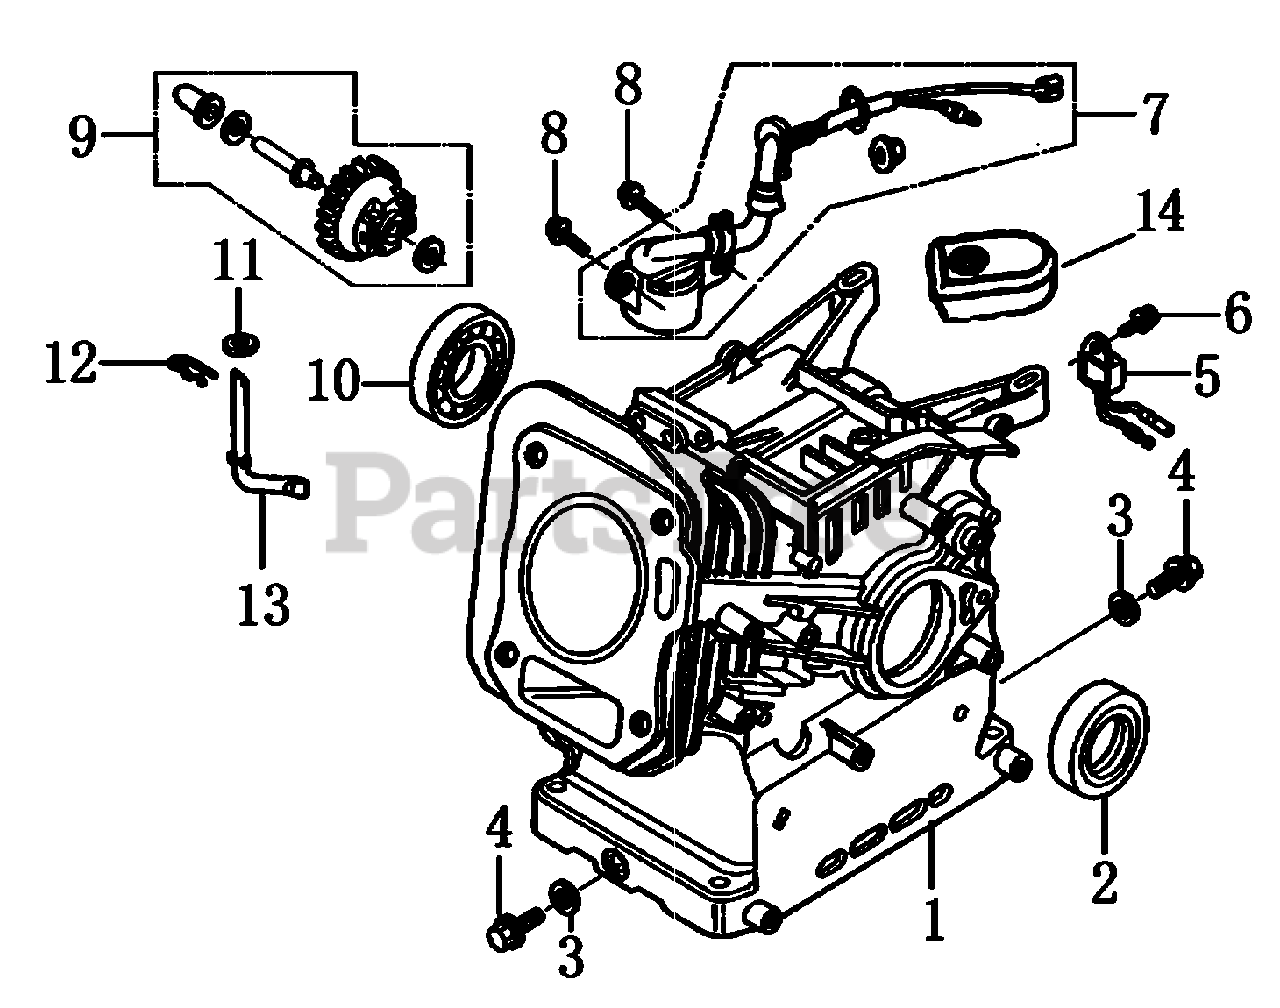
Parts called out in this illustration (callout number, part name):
1	CRANK CASE
2	OIL SEAL 25X41.25X6
3	WASHER, DRAIN PLUG
4	BOLT, DRAIN PLUG
5	OIL, LOW ALERT UNIT(GOLD)
6	BOLT, FLANGE , 6X10
7	SWITCH, OIL LEVEL
8	BOLT, FLANGE , 6*14
9	GOVERNOR GEAR ASSY.
10	BEARING, RADIAL BALL
11	WASHER, PLAIN
12	PIN, LOCK
13	SHAFT, GOVERNOR ARM
14	COVER, WIRE
